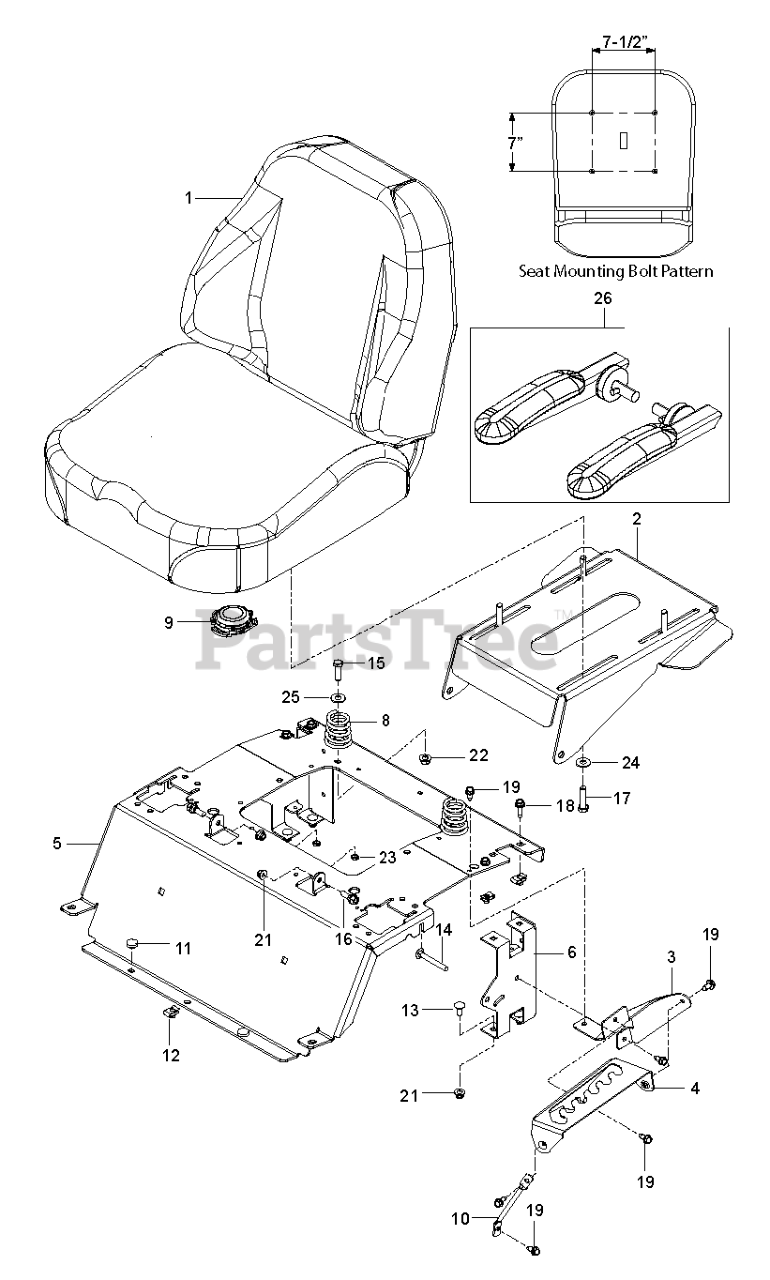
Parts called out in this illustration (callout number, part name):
1	SEAT. WOOD.BOTTOM.4-BOLT.HUSQ
2	PAN SEAT, 4-BOLT BLACK X428
3	PLATE.SUPPORT.DECK.LIFT.X431
4	PLATE.DECK.LIFT.X431
5	SUPPORT.SEAT.RZ.HUSQ.ORANGE
6	SUPPORT REAR SEAT BLACK
8	SPRING.COMPRESS.SEAT.TAPERED
9	SWITCH.SEAT.DELTA.OPC.
10	SUPPORT.LEG.DECK.LIFT
11	GROMMET.BUMPER
12	U-CLIP 5/16-18 NUT RETAINER
13	BOLT 5/16C X 3/4" CARRIAGE
14	RHSNB 5/16-18 X 2-1/2 GR5 ZD
15	BOLT
16	BOLT, SHOULDER
17	BOLT.5/16-18X1-1/4 FULL.THREAD
18	SCREW.THDROL.5/16-18X3/4.TTY
19	BOLT.5/16HEX.WHS.HD
21	5/16-18 NYLOC FLANGE NUT
22	NUT 3/8-16 HEX FLG NYLOC ZD
23	NUT
24	WASHER
25	RP WASHER 3/8 FLAT
26	SEAT KING 18" WOOD BTM, ARM
